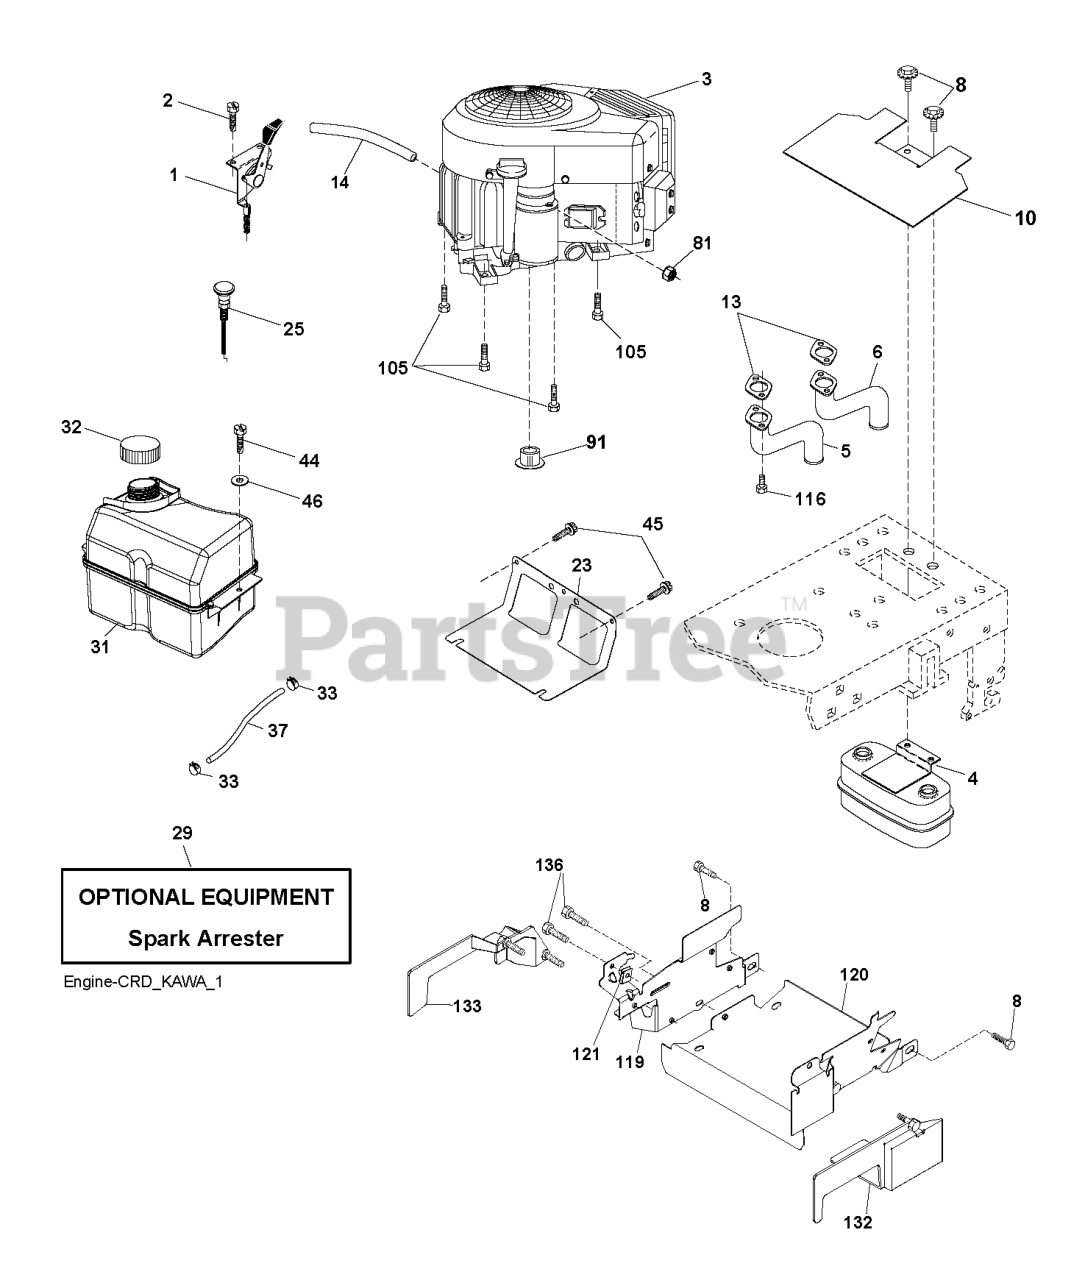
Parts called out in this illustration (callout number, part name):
1	THROTTLE CABLE
2	SCREW.#10 X 0.750.BOS
4	MUFFLER.TWIN.CYL.LOW.TONE
5	EXHAUST TUBE LH KAWI
6	EXHAUST TUBE RH KAWI
8	BOLT.5/16-18UNCX3/4 W/SEMS.BLK
10	RP SHIELD HEAT MUFFLER
13	GASKET.EXHAUST.KAWASAKI.15-1
14	TUBE, DRAIN OIL ASM.
23	SHIELD.BROWNING.DBR.GUARD
25	CONTROL, CHOKE
29	KIT.SPARK ARRESTOR 794945 B&S
31	TANK.ASM.FUEL.FR.2.5GA.
32	CAP.FUEL.2.25"VENTED"
33	HOSE CLAMP
37	LINE.FUEL.20
44	SCREW HEXWSHR 1/4-20X3/4
45	SCREW, 3/8-16X3/4
81	NUT
91	BUSHING.1.375OD
105	SCREW 3/8-16X1
116	NUT.HEX.FLANGE.TOPLOCK
119	LENKRAD
120	GUARD 532199767
132	SHIELD RIGHT
136	SCREW.1/4-20X5/8
